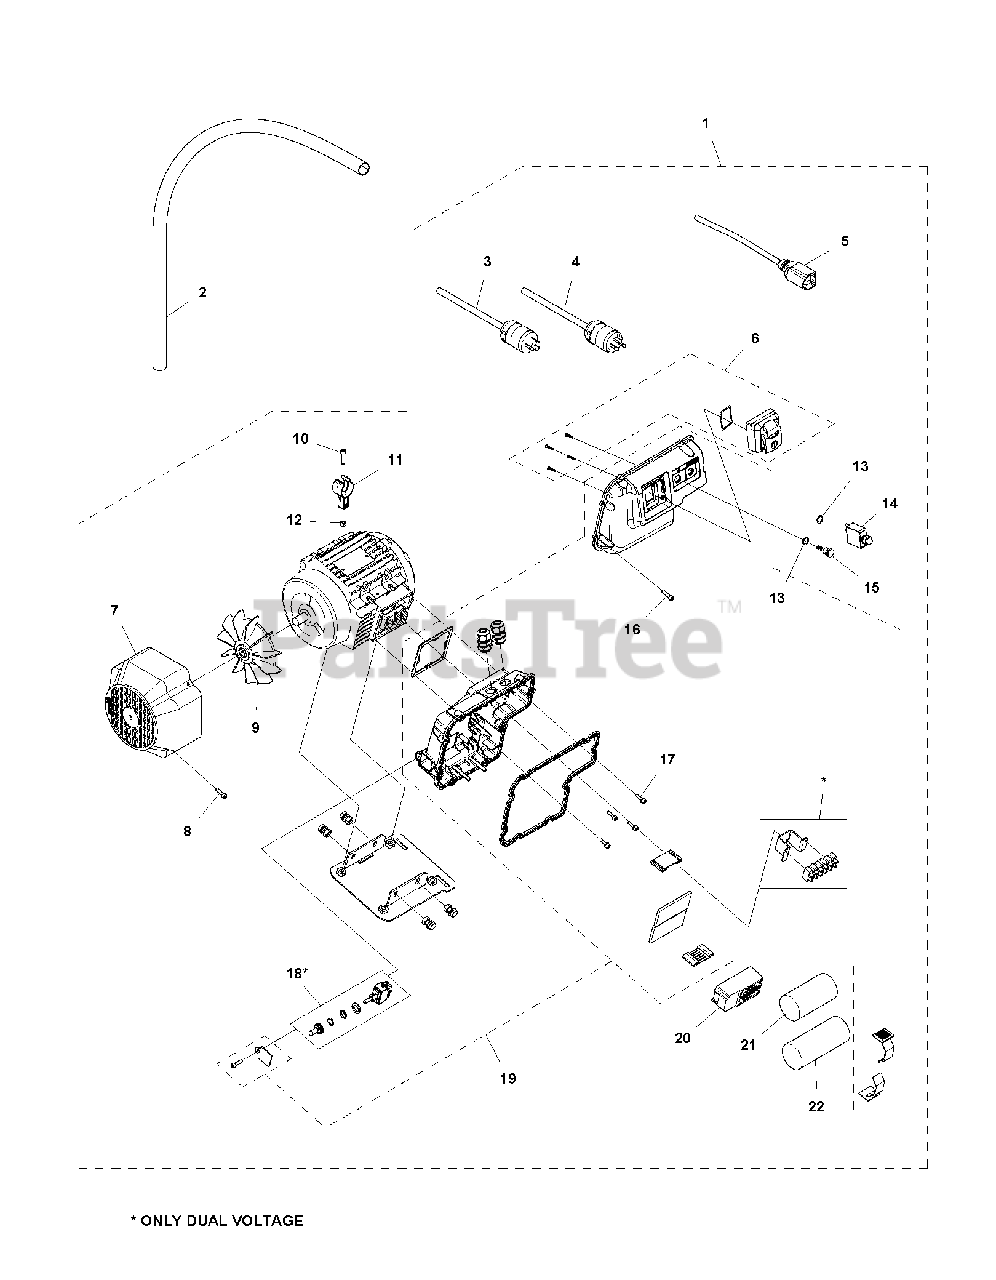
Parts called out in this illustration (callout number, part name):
1	MOTOR115V/230V,1,1 kW,60Hz CPL
1	MOTOR230V, 2.2 kW, 60Hz CPL
1	MOTOR115V/230V,1,5kW,60Hz CPL
1	MOTOR115V,1,1 kW,60Hz CPL
3	CABLEUsed for: 585 22 54-04
4	CABLEUsed for: 585 22 54-01/-02/-03
7	FAN COVERUsed for: 585 22 54-04
7	FAN COVERUsed for: 585 22 54-01/-02/-03
9	FANUsed for: 585 22 54-04
9	FANUsed for: 585 22 54-01/-02/-03
10	SCREW IHSCM
12	HEXAGON LOCKING NUT
13	O-RINGQty 3 in dual voltage
14	ADAPTERUsed for: 585 22 54-02
14	CIRCUIT BREAKERUsed for: 585 22 54-01/-04
14	CIRCUIT BREAKERUsed for: 585 22 54-03
15	LAMPUsed for: 585 22 54-02
16	SCREW IHSCM
18	SWITCH KITDual voltage
20	ELECTRONIC BOXUsed for: 585 22 54-02
21	CAPACITORUsed for: 585 22 54-01/-04
21	CAPACITORUsed for: 585 22 54-03
21	CAPACITORUsed for: 585 22 54-02
22	CAPACITORUsed for: 585 22 54-01/-04
22	CAPACITORUsed for: 585 22 54-03
22	CAPACITORUsed for: 585 22 54-02
